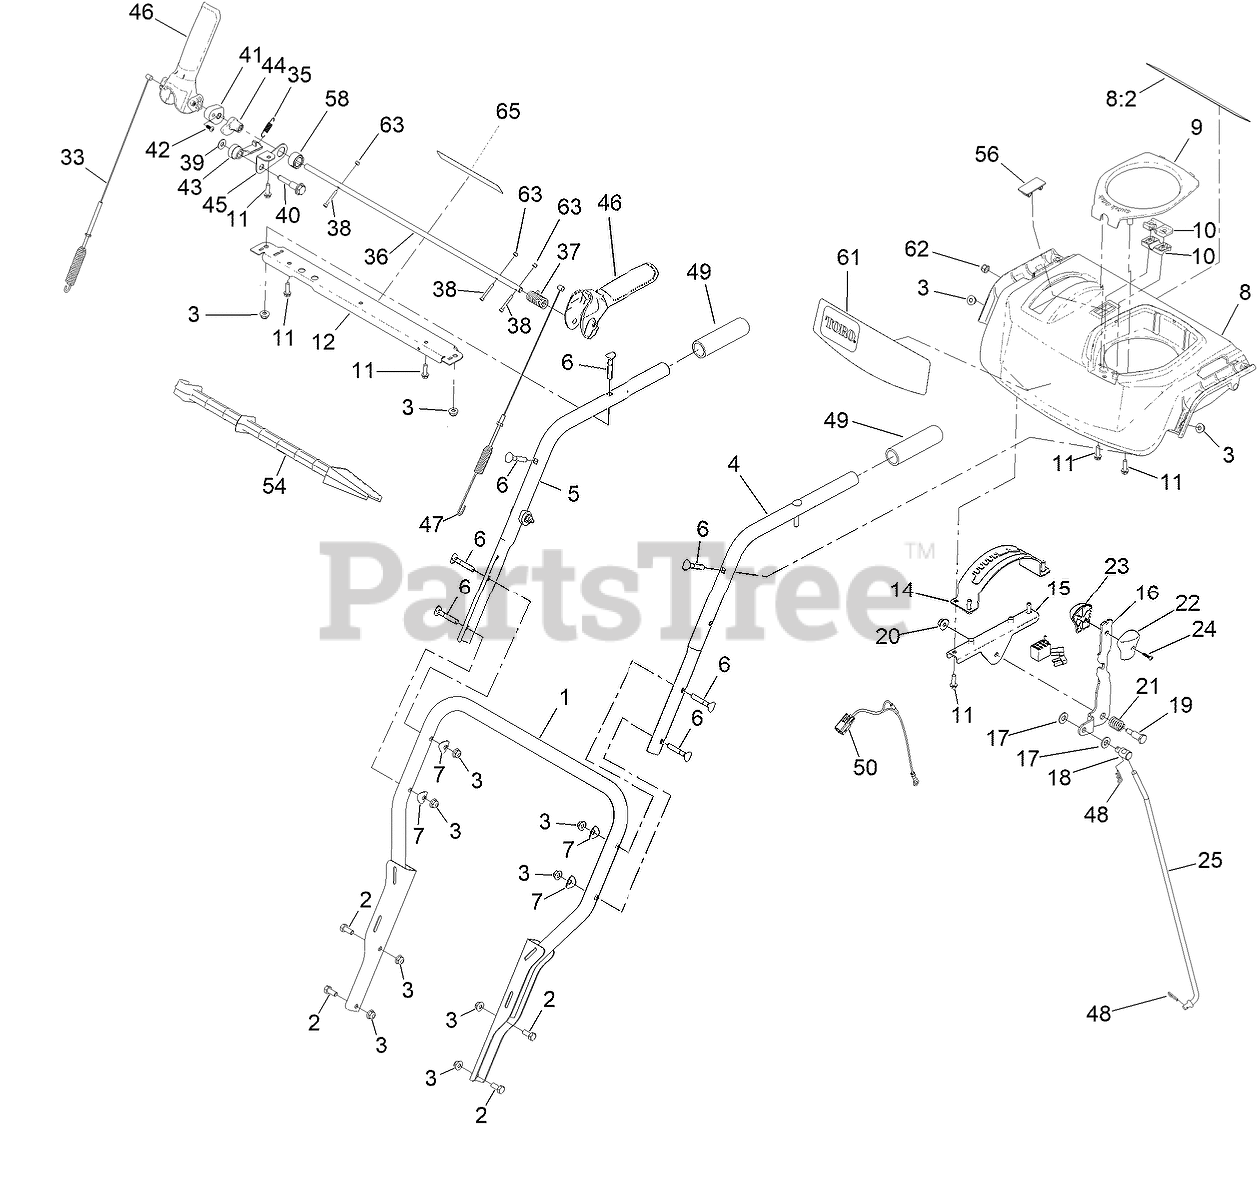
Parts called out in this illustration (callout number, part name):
1	LOWER HANDLE ASM
2	SCREW-HH
3	NUT-HF
4	HANDLE-UPPER, LH
5	HANDLE-UPPER, RH
6	SCREW-HANDLE
7	WASHER-CUP
8	CONTROL PANEL ASSEMBLY
8:2	DECAL-SAFETY
9	COVER-QUICKSTICK
10	SUPPORT-ROD
11	SCREW-PLASTITE, HWH
12	BRACE-CONSOLE
14	GATE-SHIFT
15	BRACKET-SHIFT
16	SELECTOR-SPEED
17	WASHER-FLAT
18	TRUNNION-ROD
19	SCREW-SHOULDER, HH
20	NUT-HF
21	SPRING-COMPRESSION
22	KNOB-SHIFT, LH
23	KNOB-SHIFT, RH
24	SCREW-PPH
25	ROD-SHIFT
33	CABLE-AUGER
35	SPRING-LOCKOUT, HANDLE
36	ROD-LOCKOUT
37	SPRING-TORSION, HANDLE RETURN
38	SCREW-HSH,SPL
39	WASHER-FLAT
40	SCREW-SHOULDER
41	HANDLE LOCK
42	SCREW-PPH
43	LATCH, LOCKOUT
44	CAM-LOCKOUT
45	LINK-LOCKOUT
46	LEVER-CONTROL
47	CABLE-TRACTION
48	PIN-HAIR
49	GRIP-HANDLE
50	HARNESS-WIRE, LED
54	STICK-CLEANOUT
56	PLUG-HOLE
58	COLLAR-CAM
61	DECAL-CONSOLE
62	NUT-HEX
63	NUT-LOCK ROHS
65	DECAL-HYDRO
